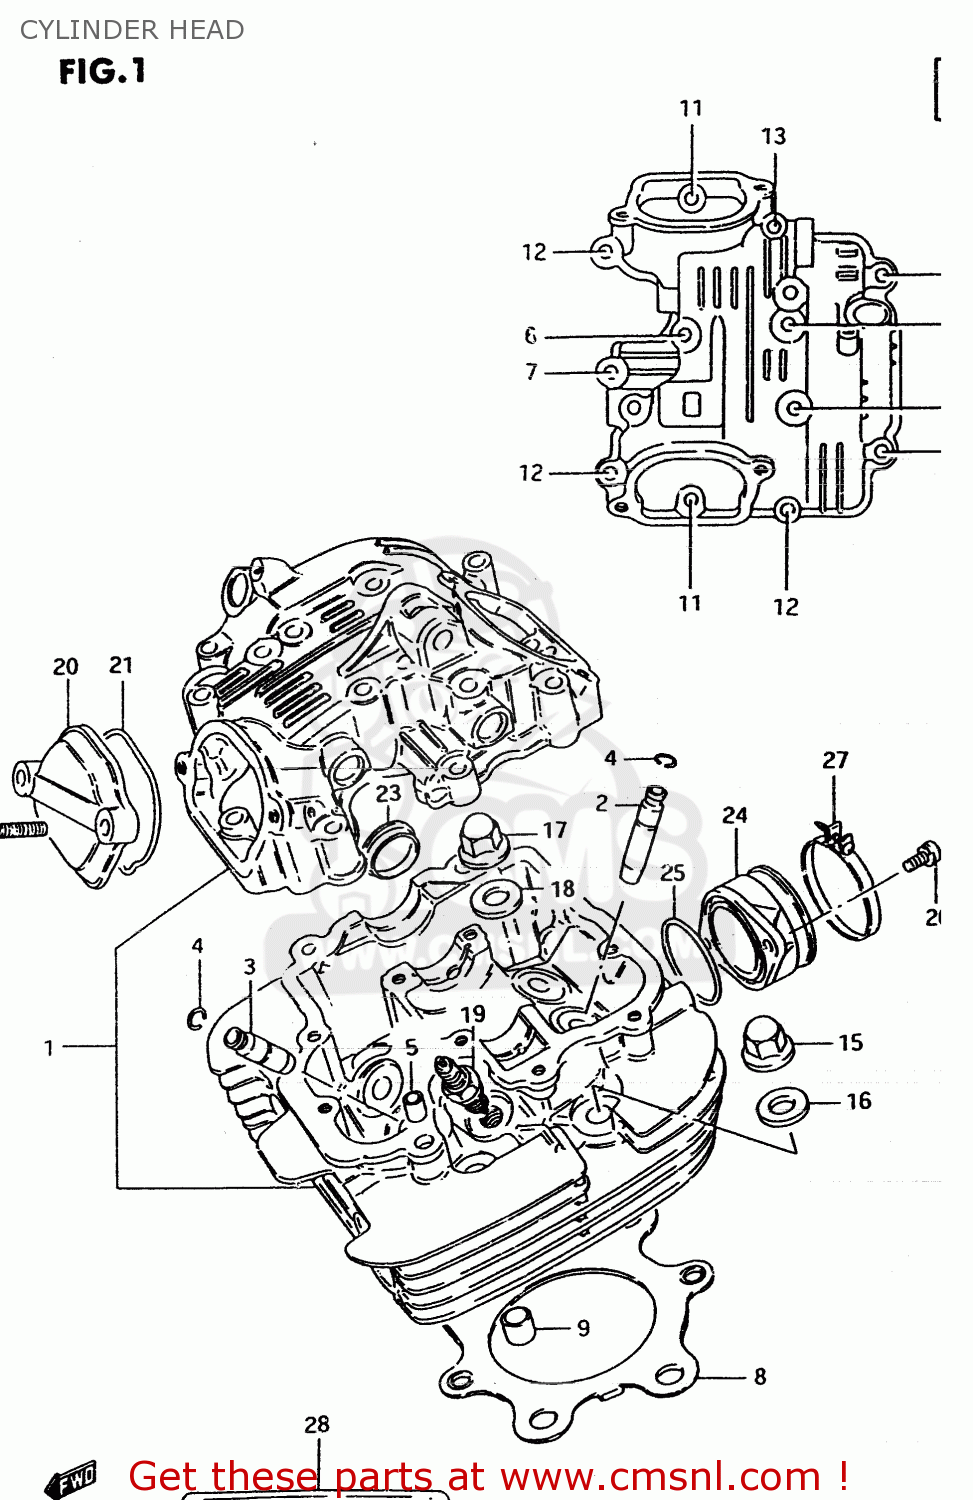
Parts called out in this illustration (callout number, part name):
1	HEAD ASSEMBLY,CYLINDER
2	GUIDE,INTAKE VALVE
3	GUIDE,VALVE
4	RING,SNAP
5	PIN(6.2X8X11)
6	BOLT
7	BOLT
8	GASKET,CYLINDER HEAD (NAS)
9	PIN
10	BOLT(6X115)
11	BOLT
12	BOLT
13	BOLT
14	GASKET(5.8X13X1.2) (NAS)
15	NUT
16	WASHER (10.5X22X2.3)
17	NUT
18	GASKET(10.5X22X2) (NAS)
19	PLUG,SPARK(DR8EA)
20	CAP,INSPECTION
21	O RING(D:2.4,ID:23)
22	BOLT
23	PLUG(OD:30)
24	PIPE,INTAKE
25	O-RING (D:2.4 ID:39.7)
26	SCREW
27	CLAMP
28	GASKET SET
